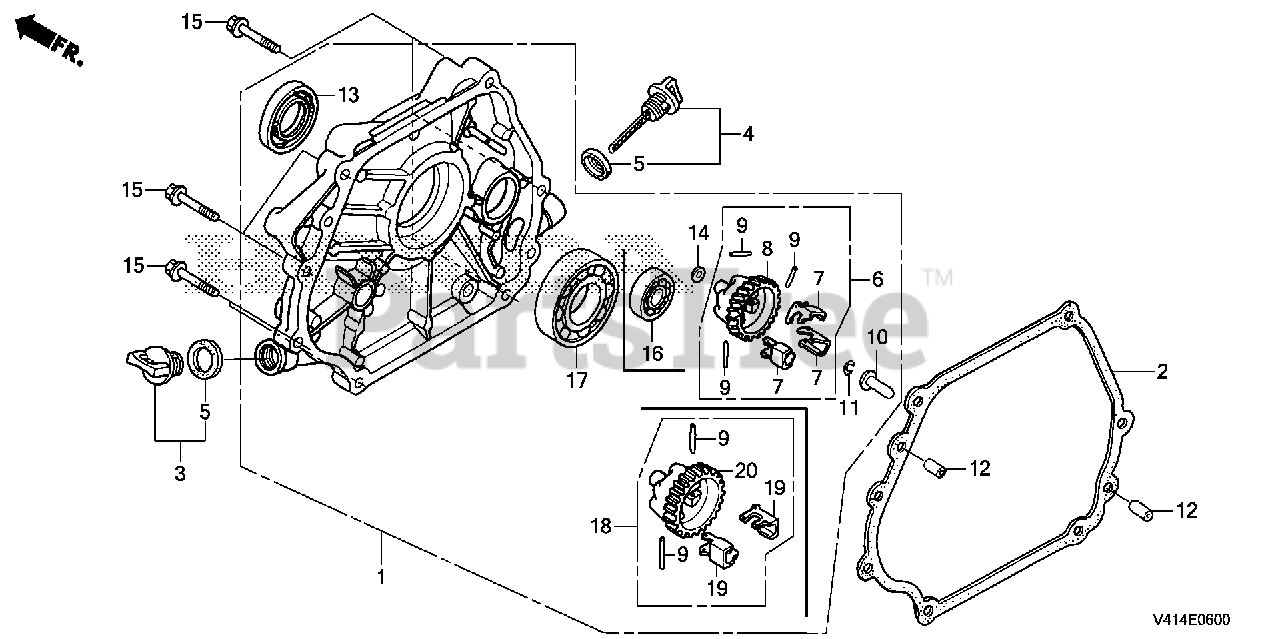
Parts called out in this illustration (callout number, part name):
1	COVER ASSY., CRANKCASE
2	GASKET, CASE COVER
3	CAP ASSY., OIL FILLER
4	CAP ASSY., OIL FILLER
5	GASKET, OIL FILLER CAP
9	PIN, GOVERNOR WEIGHT
10	SLIDER, GOVERNOR
11	CLIP, GOVERNOR HOLDER
12	PIN, DOWEL (8X12)
13	OIL SEAL (30X46X8) (NOK ASIA)
14	WASHER, PLAIN (6MM)
15	BOLT, FLANGE (8X35)
17	BEARING, RADIAL BALL (6206)
18	GOVERNOR ASSY. (STD)
19	WEIGHT, GOVERNOR
20	HOLDER, GOVERNOR WEIGHT
